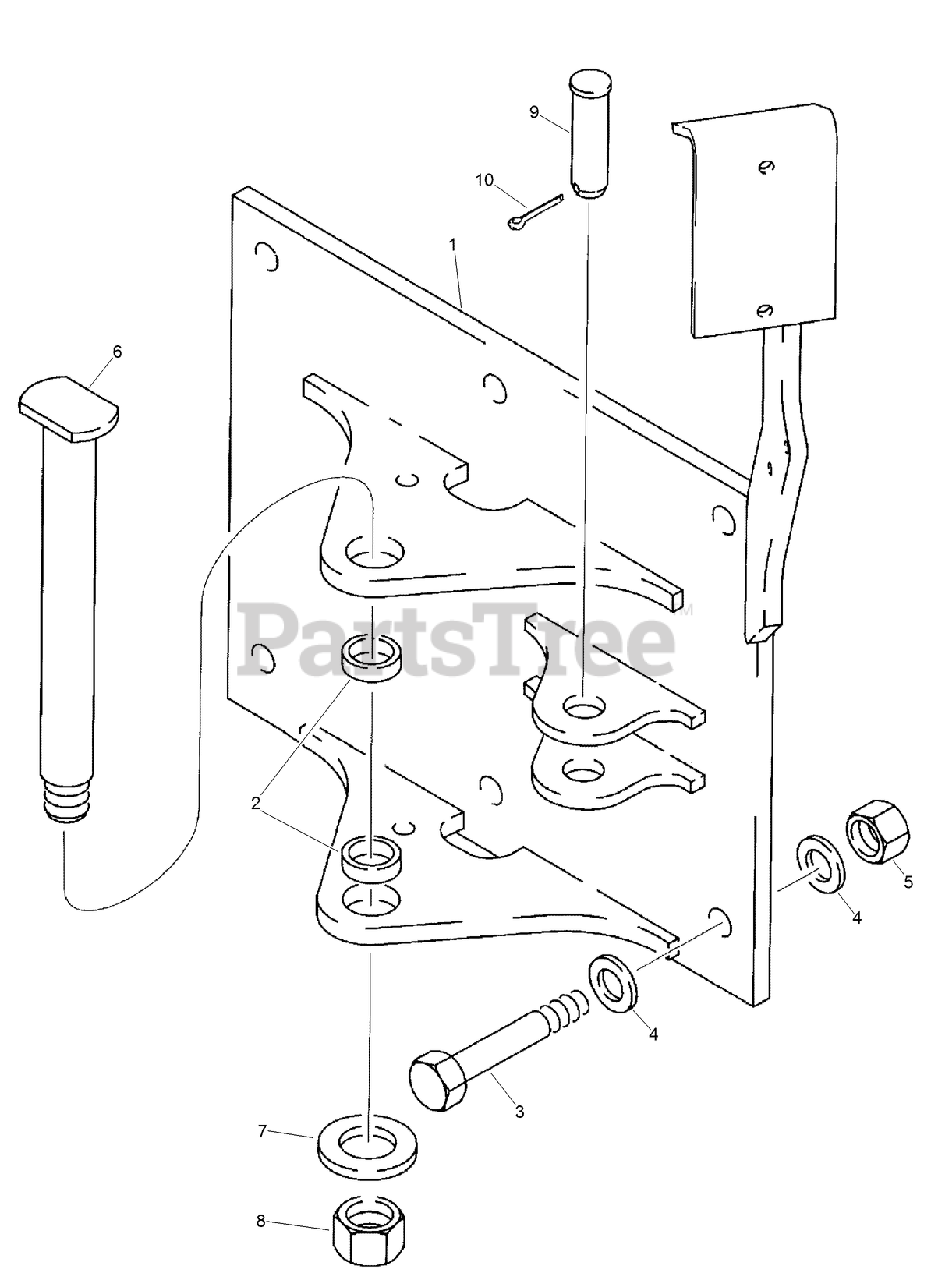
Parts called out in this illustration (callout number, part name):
1	BRACKET-mounting, plow to basic machine
2	BUSHING-pivot plate
4	WASHER-flat, special, 3/4 inch
5	NUT-Prev Trq 3/4 GRC CAD Direct
6	PIN-pivot, plow
7	WASHER-flat, 1-17/32 x 2-1/16 x 1/8 inch
9	PIN-clevis, 1 x 3-1/2 inch, hardened
10	PIN-cotter, 5/32 x 1-3/4 inch
